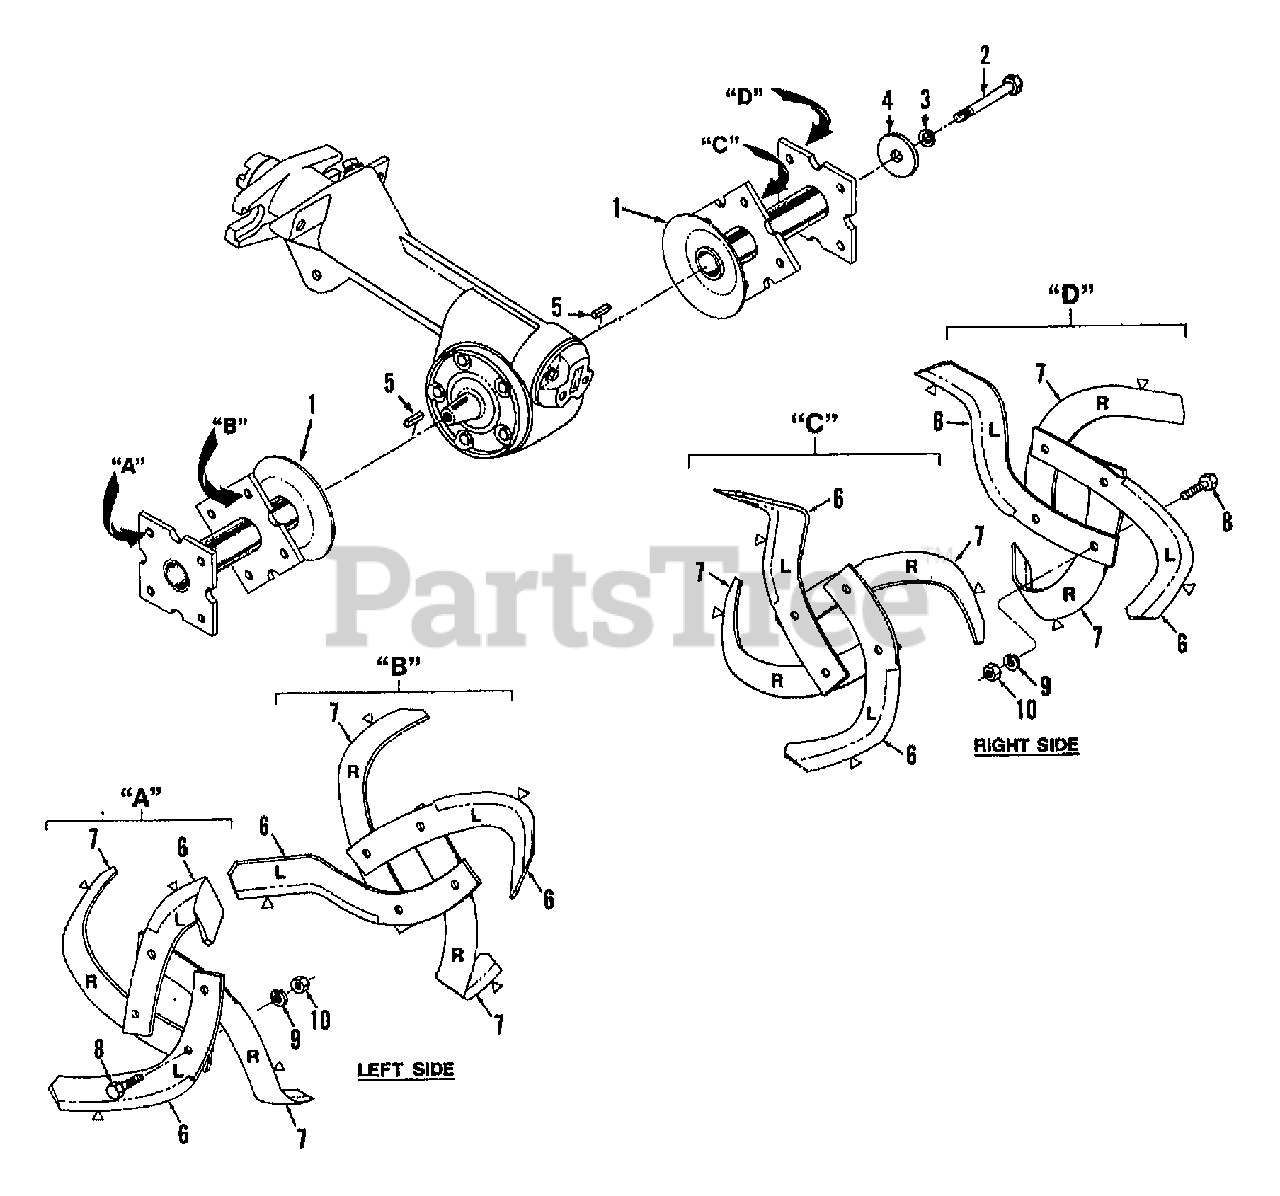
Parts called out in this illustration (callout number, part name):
1	HOLDER-TINE RED
2	SCR-HH 1/2-20X4.75 GR5
3	WASHER-LK .5
4	WASHER-1.5X.531X.187
5	KEY-.188 SQX1.0
6	TINE-BOLO LT W/HDW
7	TINE-BOLO RT W/HDW
8	SCR-HH 3/8-16X1.0 G5 ZP
9	WASHER-LK .375 @ DEPL
10	NUT-HEX 3/8-16 ZP
